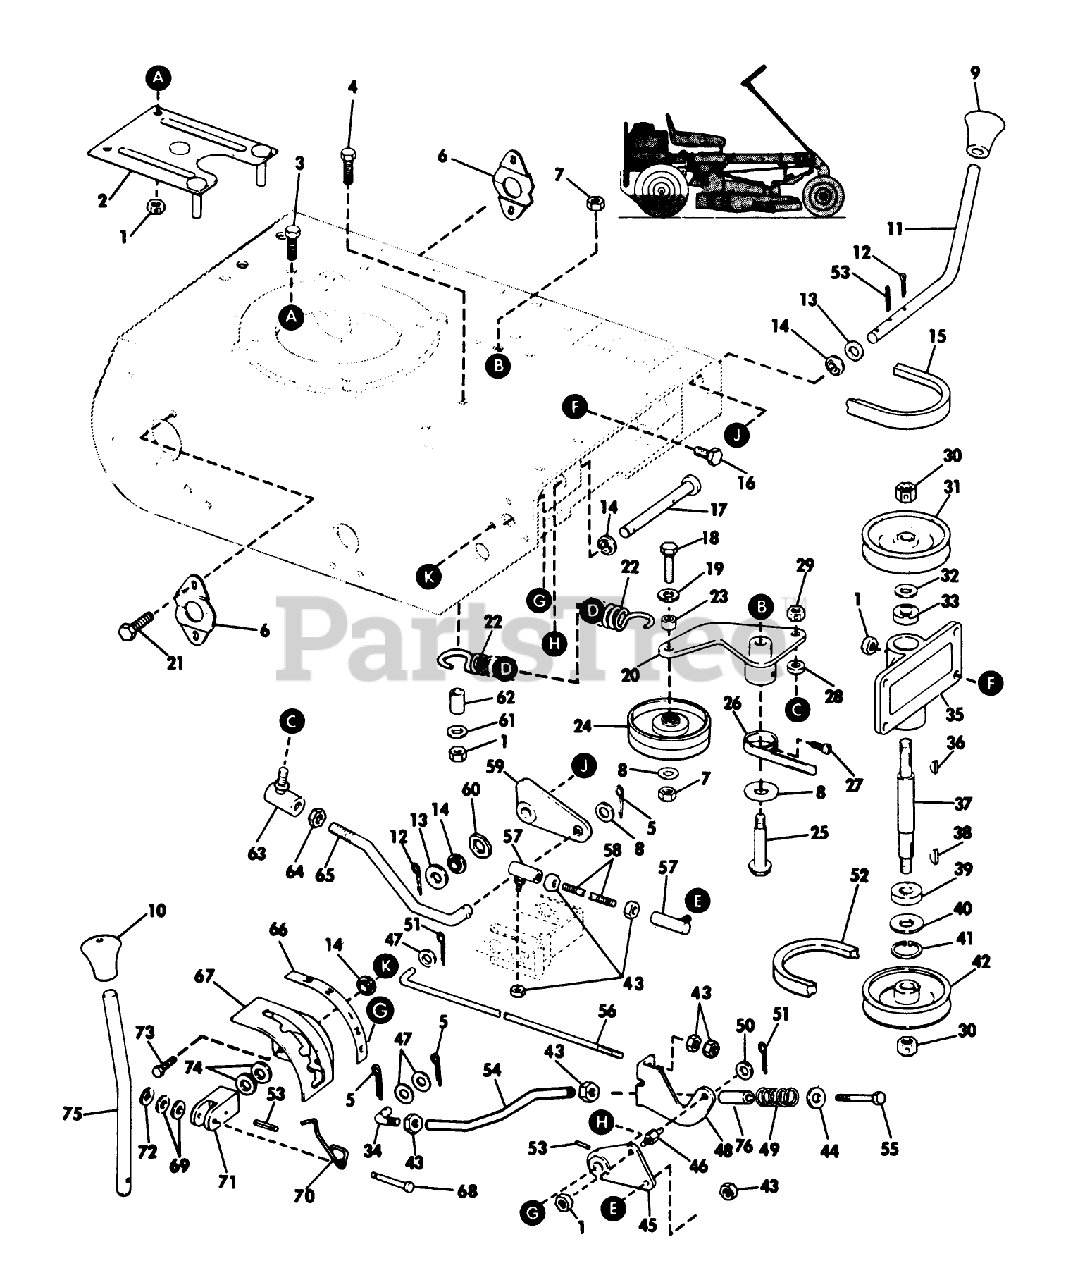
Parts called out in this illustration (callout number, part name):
7	LOCKNUT
12	Cotter Pin
43	STOP NUT
55	Screw-Reverse Booster Spring
